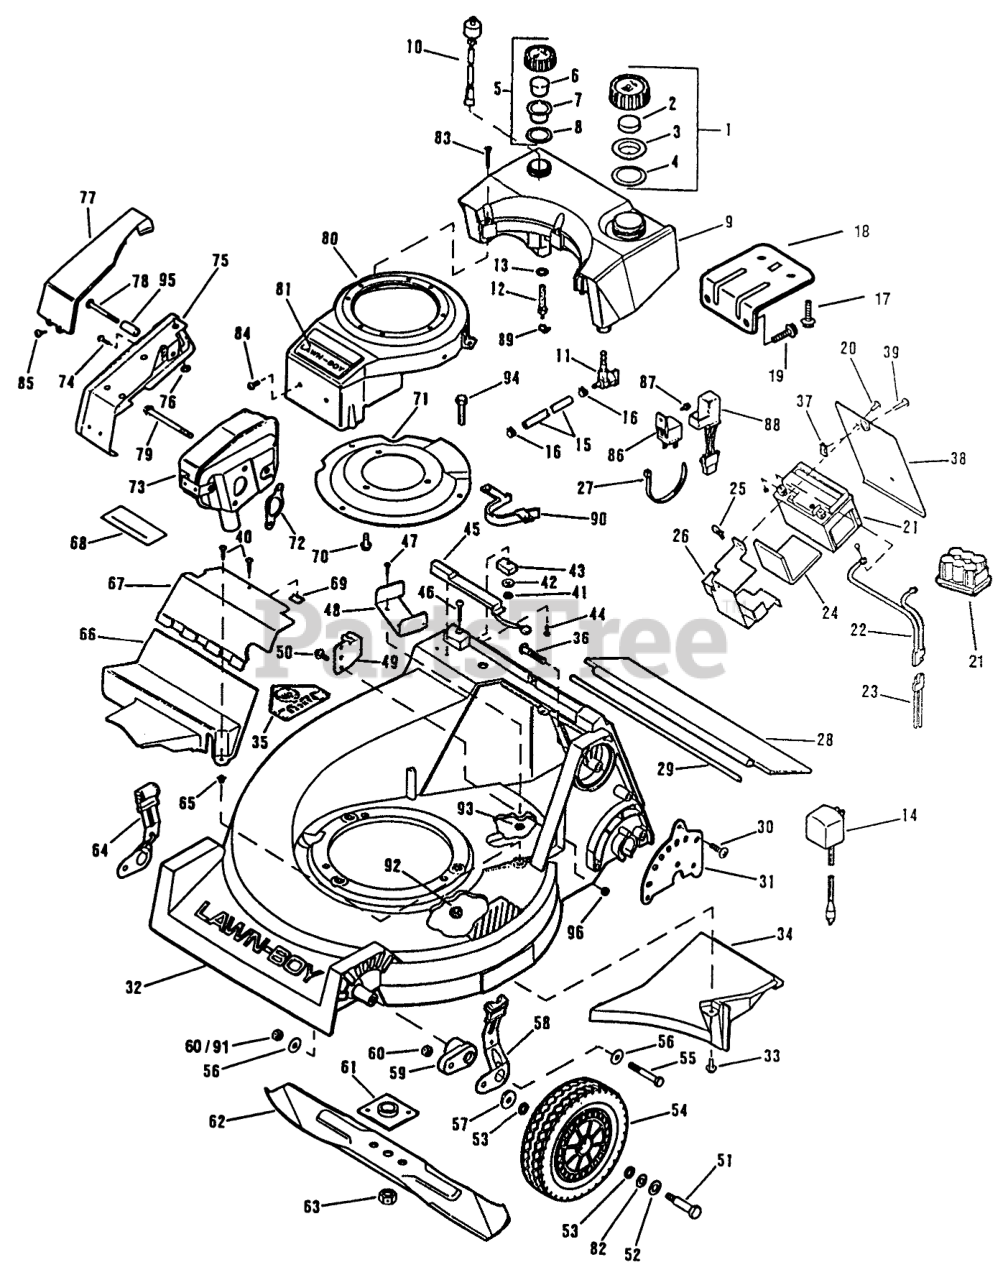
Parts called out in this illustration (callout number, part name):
1	CAP AY - FUEL M
2	BAFFLE - FOAM SM
3	Cover
4	GASKET-FUELCAP SM
5	CAP AY. OIL M
6	FILTER S
7	Cover
8	GASKET, OILCAP SM
9	Fuel/Oil Tank
9	Fuel/Oil Tank (BMRC & D)
10	SWITCH AY-OIL S
10	SWITCH AY,OIL S
11	Shut-OffValve-Fuel
12	OIL FITTING/FIL SM
13	O-RING SM
14	Battery Charger
15	GAS LINE SM
16	HOSE CLAMP SM
17	Screw
18	Fuel Tank Bracket
19	SCREW-HEX W.H. SM
20	Bolt
21	Battery-12V
22	HARNESS AY-BATT
23	WIRE HARNESS
24	PAD-BATTERY
25	SPEED NUT ARDEN
26	BRACKET B'TRY ARGO
27	TIE-CABLE
27	Tie Wrap
28	Trailing Shied
29	ROD ADVANCE
30	SCREW-BUTTON HEAD
31	PLATE HGT CMS
32	Housing Assy
32	Housing Assembly
33	Screw
34	CHUTE BAFFLE NYL
35	Decal
36	BOLT - RIBBED NECK
37	SPEED NUT LARSON
38	DOOR-ACCESS ELECT.
39	SCREW-CROSS RECESS
40	SCREW S
41	NUT
42	LOCKWASHER #10
43	MAGNET ASSY
44	SCREW-STAINLESS
45	SWITCH ASSEMBLY
46	SCREW
47	SCREW TH FORM TEB
48	Belt Guide
49	ANCHOR-CABLE
50	Screw
51	BOLT WHEEL QUAL
52	WASHER-PLAIN
53	WASHER
54	WHEEL&TIRE 8" TRI
55	SCREW - HEX HEAD
56	WASHER PLAIN
57	WASHER
58	KNOB & SPRING CMS
59	ARM HGT ADJ BLACK
60	NUT-JAM, LOCKING
61	PLATE AND COLLAR ASM
62	21" Blade
63	NUT-BLADE
64	KNOB & SPRING CMS
65	NUT-CLIP
66	COVER-DRIVE-LOWER
67	COVER-UPPER
68	DECAL
69	NUT-SPEED
70	SCREW SM
71	PLATE SM
72	GASKET - EXH SM
73	Muffler
74	SCREW S
75	MUFFLER GUARD AY
76	NUT-PUSH
77	COVER MUFFLER CP
78	SCREW SM
79	SCREW-SEMS
80	Shroud and Applique
81	APPLIQUE SM
82	WASHER
83	Screw-FuelTank
84	SCREW SM
85	SCREW SM
86	RELAY E
87	SCREW SM
88	ELECTRONIC CUP ASSY. E
89	CLAMP SM
90	GUIDE-BELT SM
91	NUT
92	NUT-LOCK F
93	NUT C/LOCK E
94	SCREW-HH
95	SPACER S
96	LOCKNUT E
